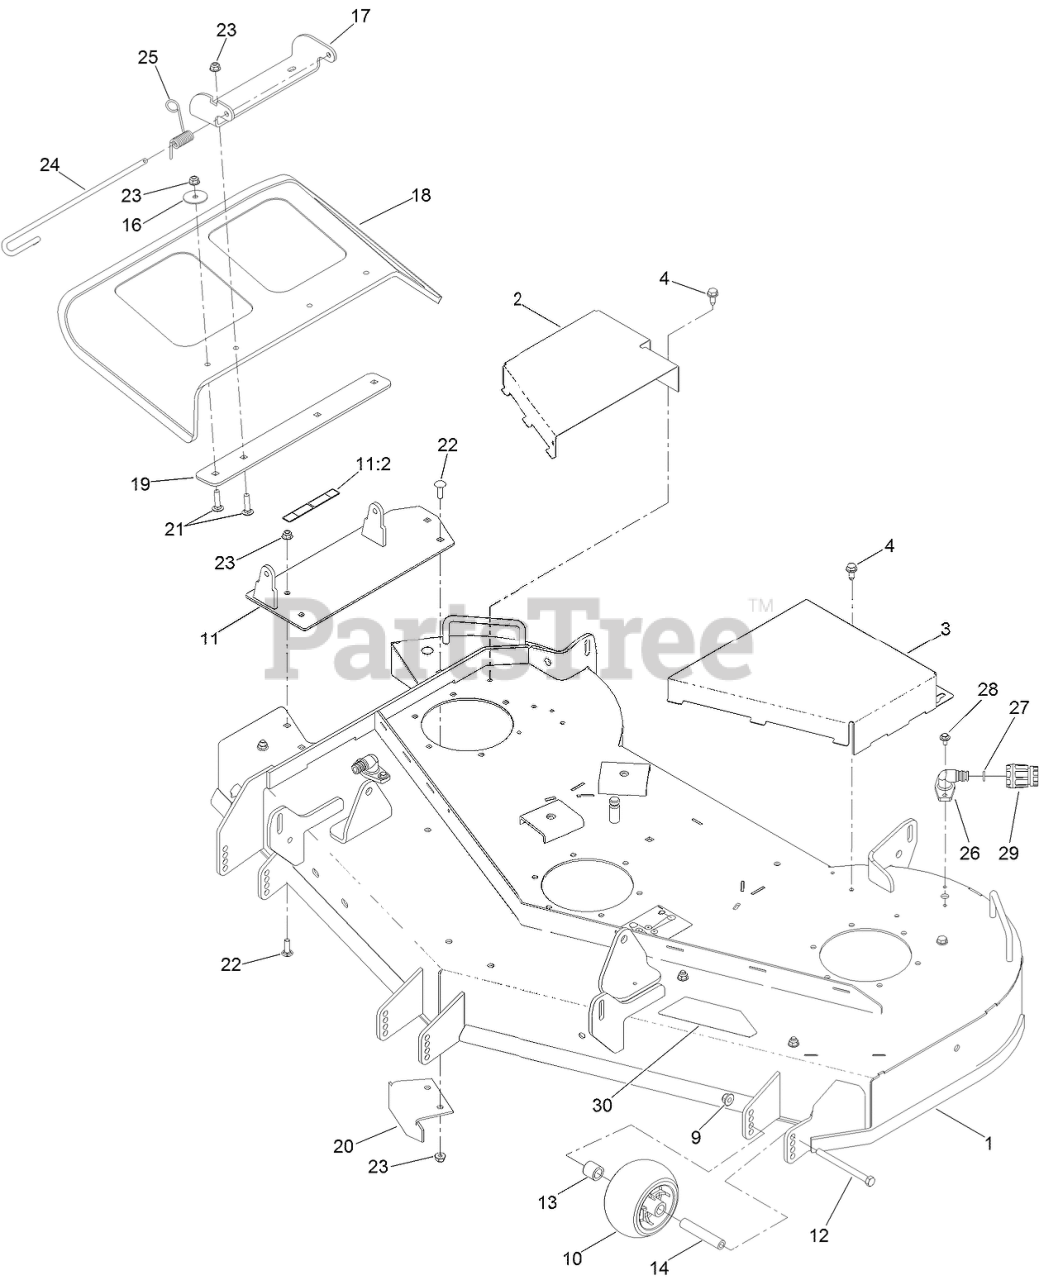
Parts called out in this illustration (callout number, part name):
1	54 INCH DECK ASM
2	COVER-BELT, RH
3	COVER-BELT, LH
4	SCREW-HWHTF
9	NUT-HF, NI
10	ROLLER-SCALP, ANTI
11	PIVOT-DEFLECTOR
11:2	DECAL-DANGER
12	SCREW-HH
13	SPACER-AXLE, REAR
14	TUBE-SPANNER
16	WASHER-FLAT
17	BRACKET-DEFLECTOR, UPPER
18	DEFLECTOR
19	PLATE-DEFLECTOR
20	BAFFLE-CUTOFF
21	SCREW-CARR
22	SCREW-CARR
23	NUT-HF, NI
24	PIN-CHUTE
25	SPRING-TORSION
26	FITTING-WASHOUT
27	O-RING
28	SCREW-HHFTF
29	CONNECTOR-HOSE
